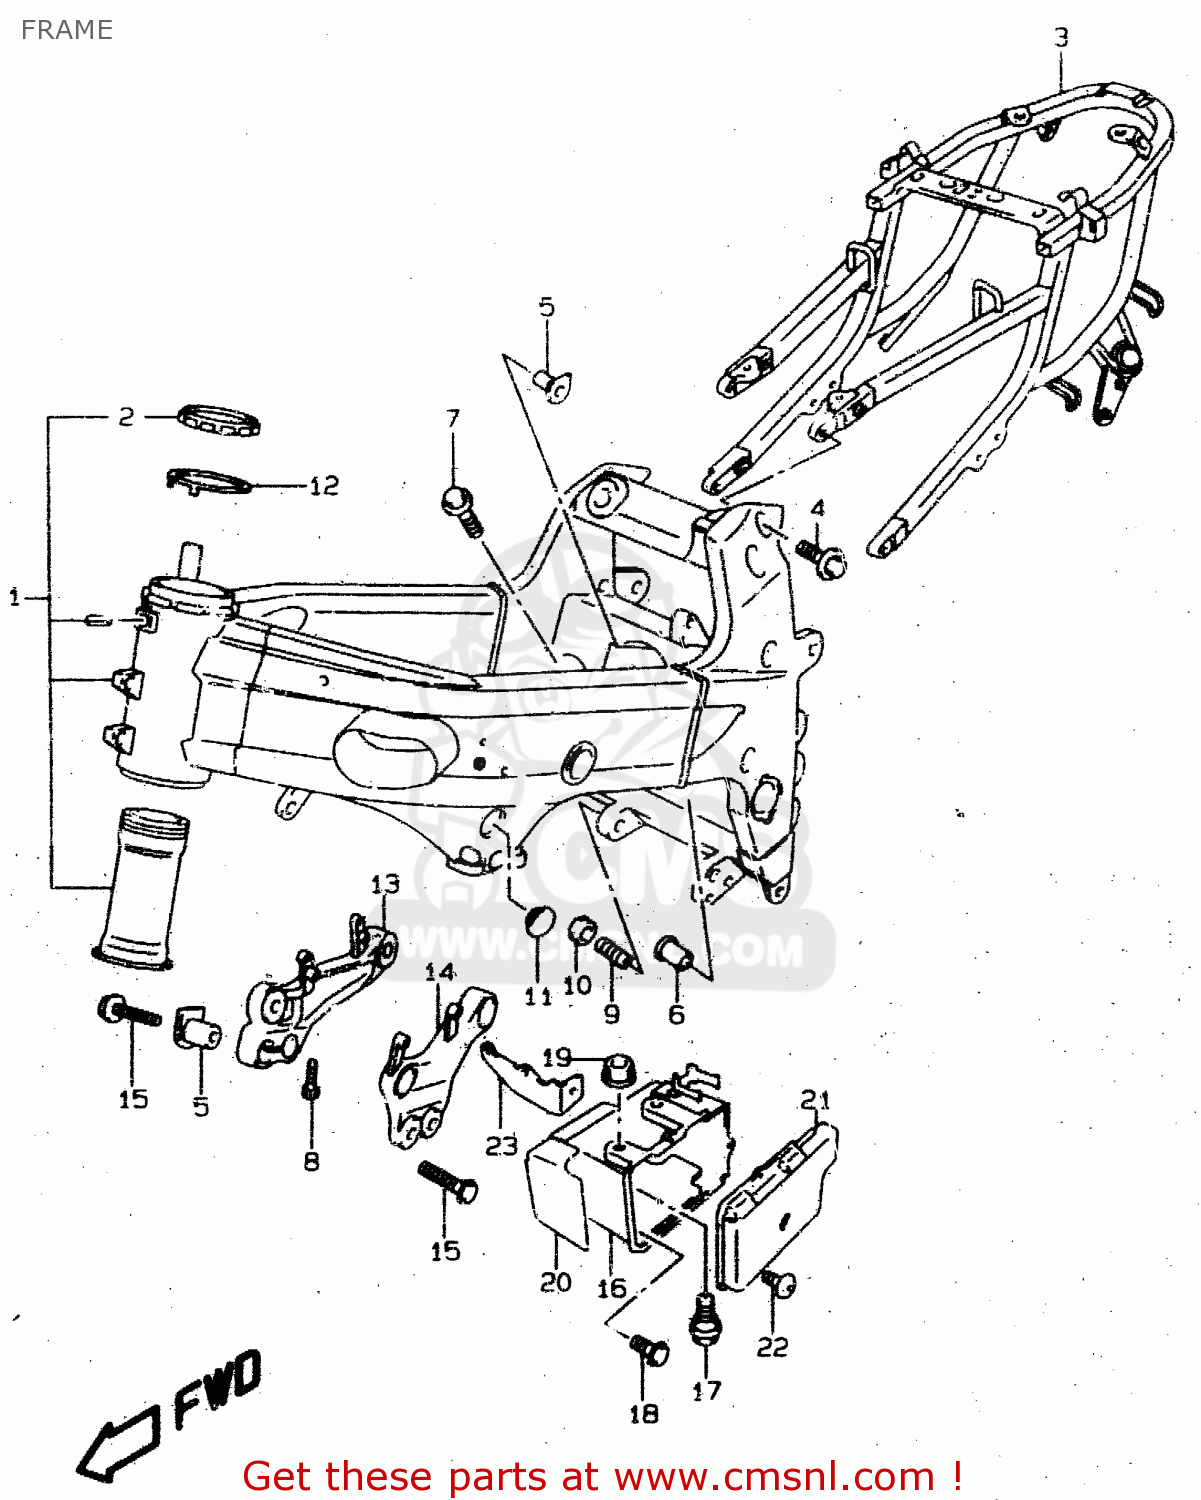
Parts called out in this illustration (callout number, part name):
1	FRAME SET
2	NUT,STEERING STEM PIPE
3	RAIL,SEAT
4	BOLT(10X30)
5	SPACER,ENG MTG FR,R
6	SPACER,ENG MTG RR UP,R
7	BOLT
8	BOLT
9	BOLT,CRANKCASE ADJUST
10	NUT,CRANKCASE ADJUST
11	CAP
12	PLATE,STEERING STEM NUT LOCK
13	BRACKET,ENGINE MOUNTING FR,R
14	BRACKET,ENGINE MOUNTING FR,L
15	BOLT
16	HOLDER,BATTERY
17	BOLT
18	BOLT(6X16)
19	NUT
20	SHIELD,BATTERY HOLDER HEAT
21	CAP,BATTERY HOLDER
22	SCREW 5X12
23	PLATE,BATTERY HOLDER LWR
